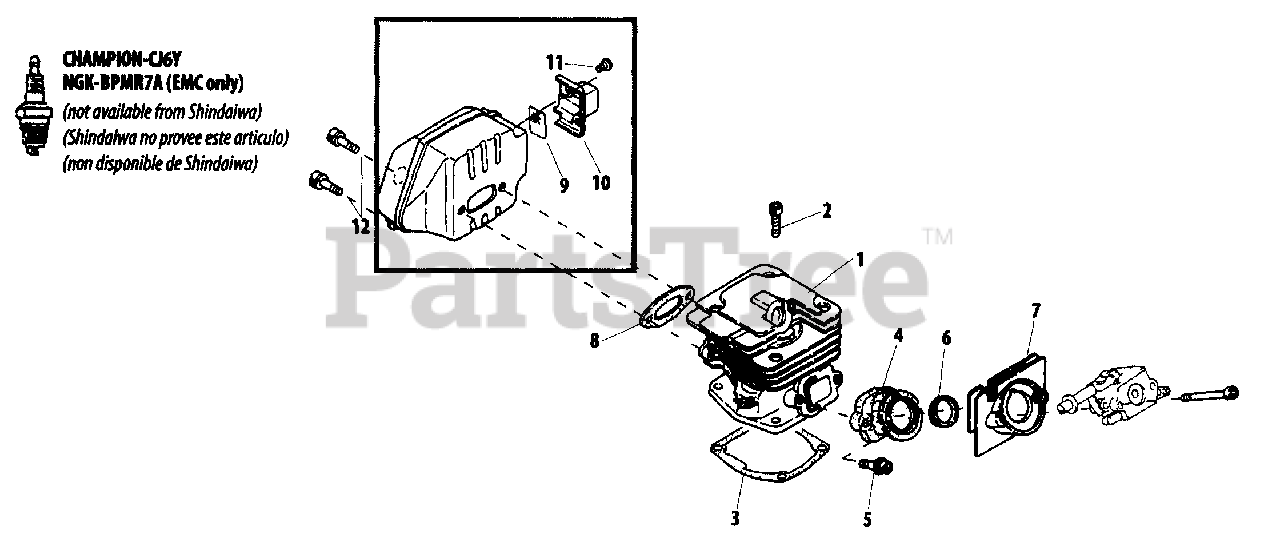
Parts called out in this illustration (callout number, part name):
1	CYLINDER
3	GASKET, CYLINDER
4	BOOT
5	SCREW - 4X14
6	SLEEVE
7	BRACKET
8	GASKET, EXHAUST
9	SCREEN, SPARK ARRESTOR
10	GUIDE, EXHAUST
11	SCREW - 4X6
12	SCREW - 5X16
